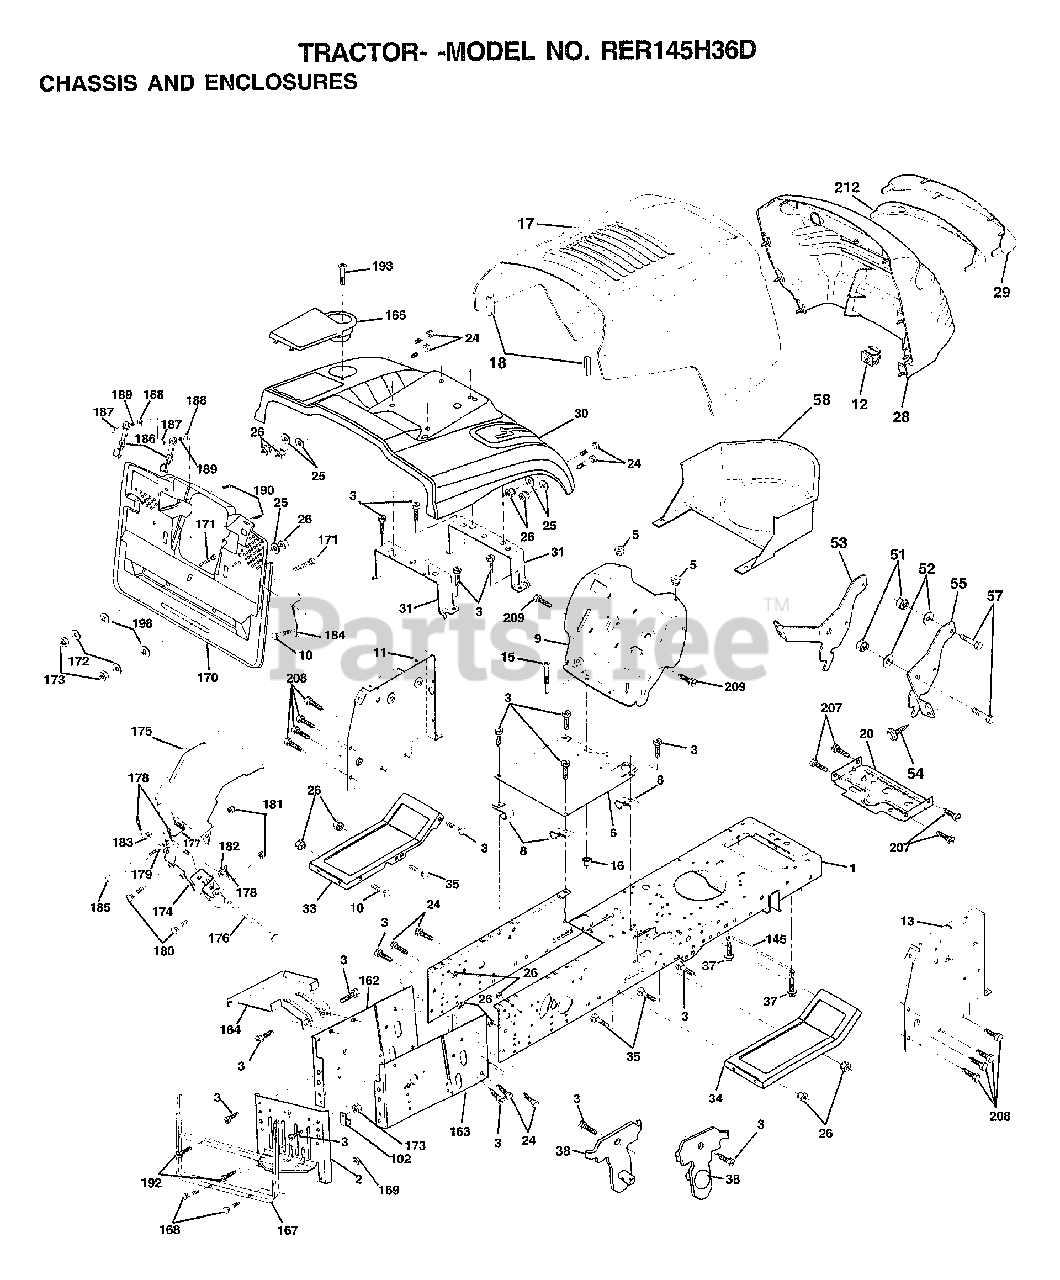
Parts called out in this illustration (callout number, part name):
2	DRAWBAR.CRD
3	SCREW
5	BUMPER-HOOD/DASH
6	SADDLE
8	"CLIP,INSULATOR"
9	DASH
11	"PANEL-DASH,LH"
12	CLIP.TINNERMAN
15	SCREW
17	HOOD.STEEL.ASSY
20	"PLATE-MTG,BATT/FU"
24	BOLT
25	WASHER
26	NUT
28	GRILL.BLK
29	LENS.GRILLE.PRIVATE LABEL
31	BRKT.SUPT.FENDER.CRD
33	FOOTREST LH
34	FOOTREST RH
35	BOLT
37	SCREW LT
38	BRKT ASM PIVOT MOWER REAR
51	NUT
52	WASHER
53	BRACKET.GRILLE.LH
54	SCREW.HEX.WS.HD
55	BRACKET.GRILLE.RH
58	AIR DUCT
102	CLIP T
145	"ROD POVOT,CHASSIS"
162	BRKT.EXT.CHASSIS.LH.CRD
163	BRKT.EXT.CHASSIS.RH.CRD
164	SUPPORT.BATTERY.CRD
165	COVER.BATTERY.CRD.BLACK.LT
167	SUPT.ASM.BACKPLATE
168	BOLT-RD HD SQ NK
170	COVER.BACKPLATE.BLACK
171	BOLT.HEX.3/8-16X2-1/2
173	NUT
174	BRKT.SWITCH.FBI.CRD
175	GRUARD.DOOR.REAR.CRD
176	HINGE PIN
177	SPRING.COVER.LH
179	ROD.PIVOT.FBI.CRD
182	WASHER.385X.625
183	WASHER
184	BRKT.ACTUATOR.BAG.CRD
185	TUBE.LEVER.SWCH.FBI.CRD
186	LATCH ASSY.BAGGER
187	WELDNUT
188	WASHER #10
189	LOCKWASHER
190	SCREW
192	SCREW LT
193	SCREW
198	NUT PUSH
207	SCREW
208	SCREW
209	SCREW
212	INSERT LENS REFLECT
